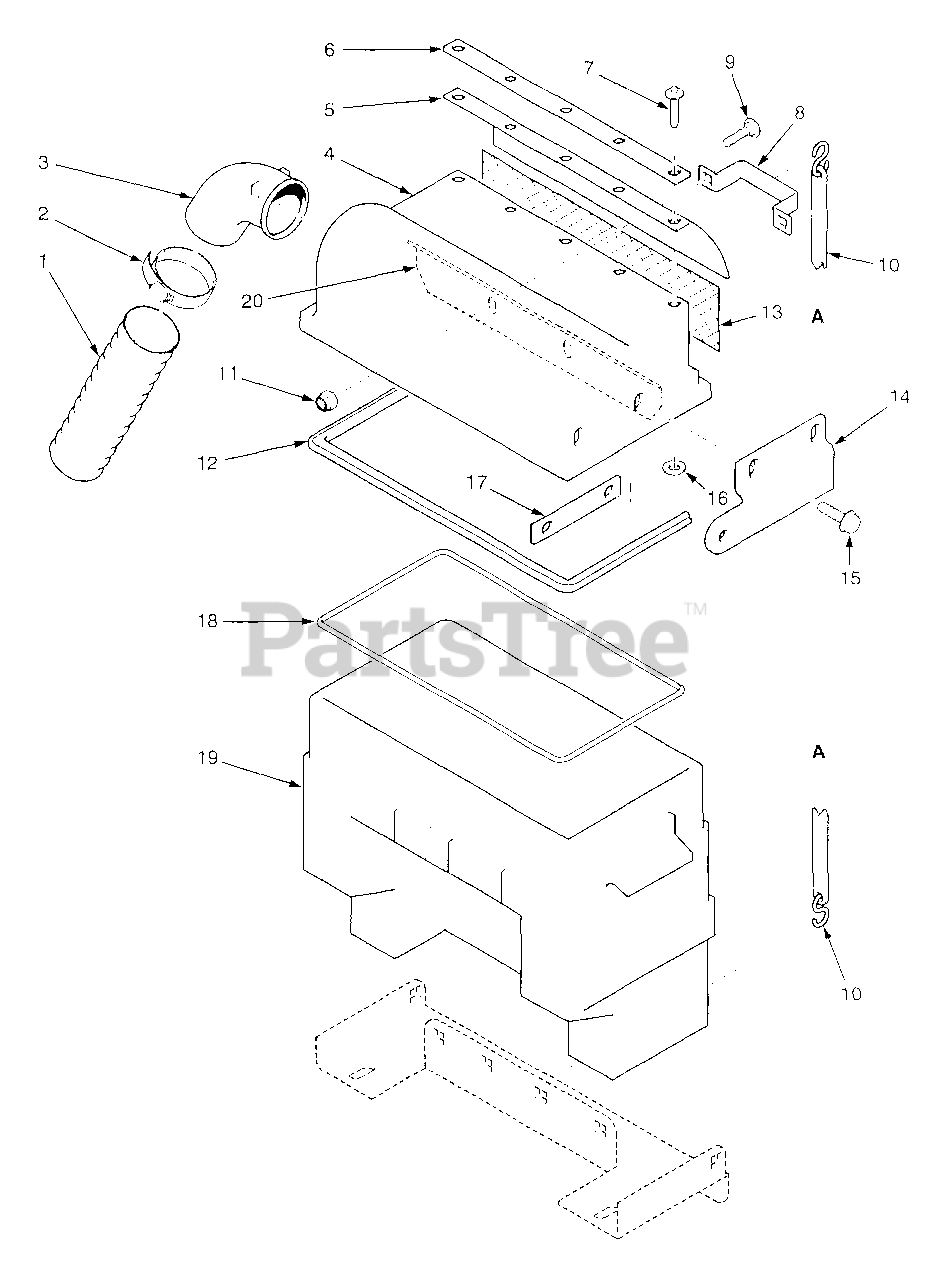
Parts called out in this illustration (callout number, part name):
1	Hose, 6" x 48"
2	Clamp, Hose
3	Elbow, Grass Catcher
4	Cover Assembly, Grass Catcher
5	Deflector, Grass Catcher
6	Backing Plate, Deflector
8	Handle
9	Bolt, 5/16-18 x .75" Carriage
10	Strap, Rubber
11	Nut, 5/16-18 Elastic Stop
12	Seal Rubber
13	Screen
14	Hinge, Left Hand
15	Capscrew, 5/16-18 x .75" Serrated Flange
16	Washer, Pop Rivet
17	Plate, Hinge Backing
18	Stiffener, Grass Catcher Hopper
19	Hopper Assy., Grass Catcher With Decal
20	Backing Plate, Handle
